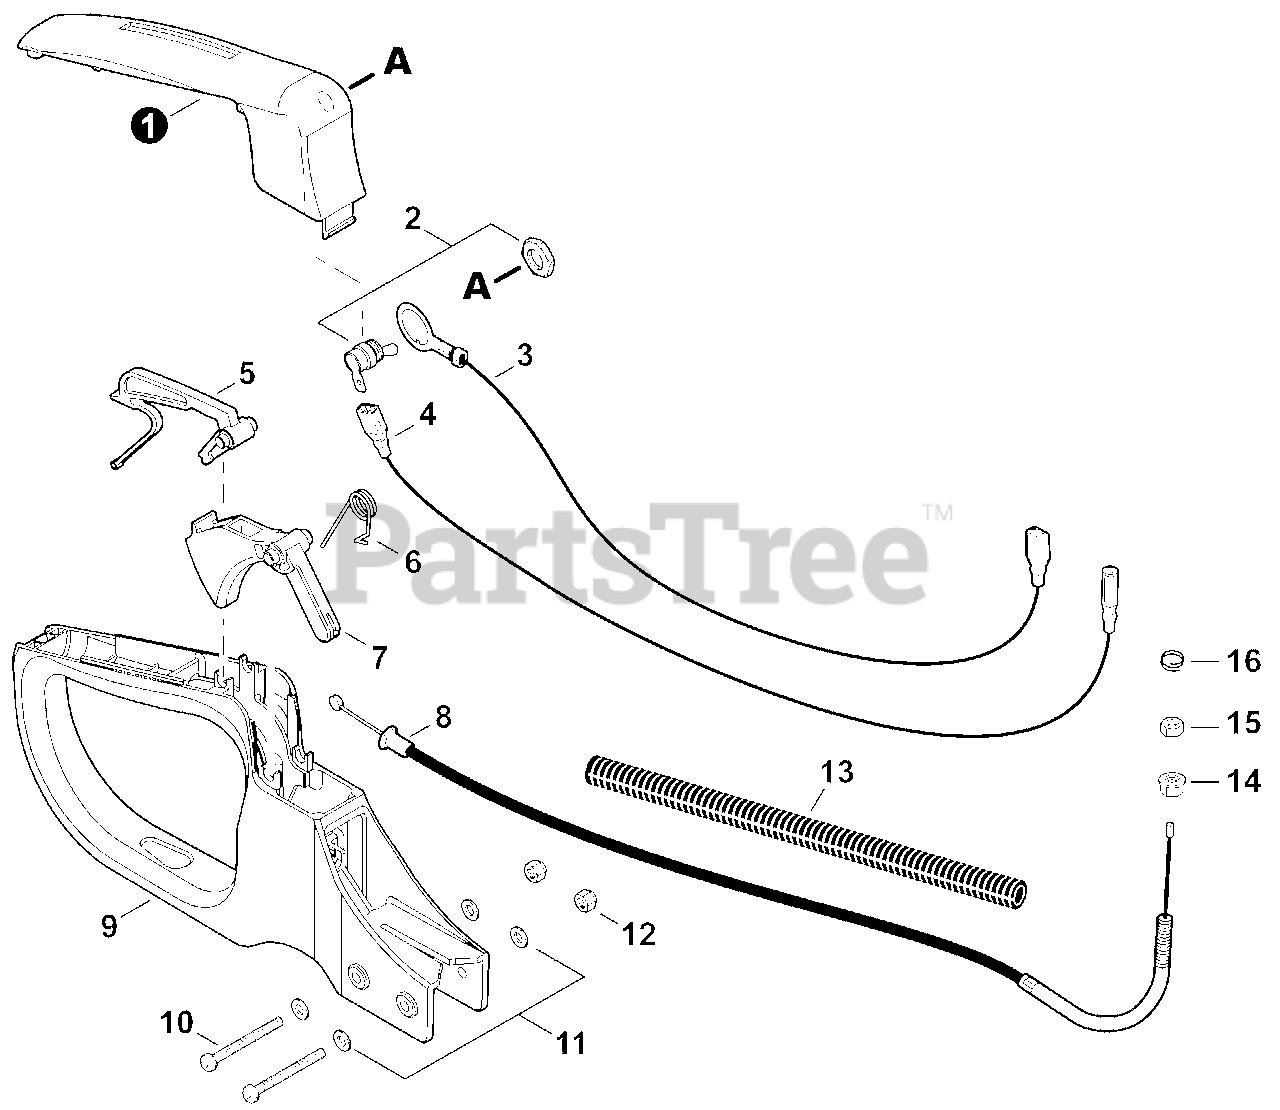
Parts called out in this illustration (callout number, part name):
1	COVER, HANDLE
2	SWITCH, ON-OFF
3	LEAD - GROUND
4	LEAD - IGNITION
5	LOCKOUT, THROTTLE
6	SPRING, TORSION
7	TRIGGER, THROTTLE
8	CABLE, THROTTLE
9	HANDLE, REAR
10	SCREW 5×45
11	WASHER, FLAT 5.5×10×0.8
12	NUT, LOCK M5
13	TUBE, FLEXIBLE
14	NUT, FLANGE M6
